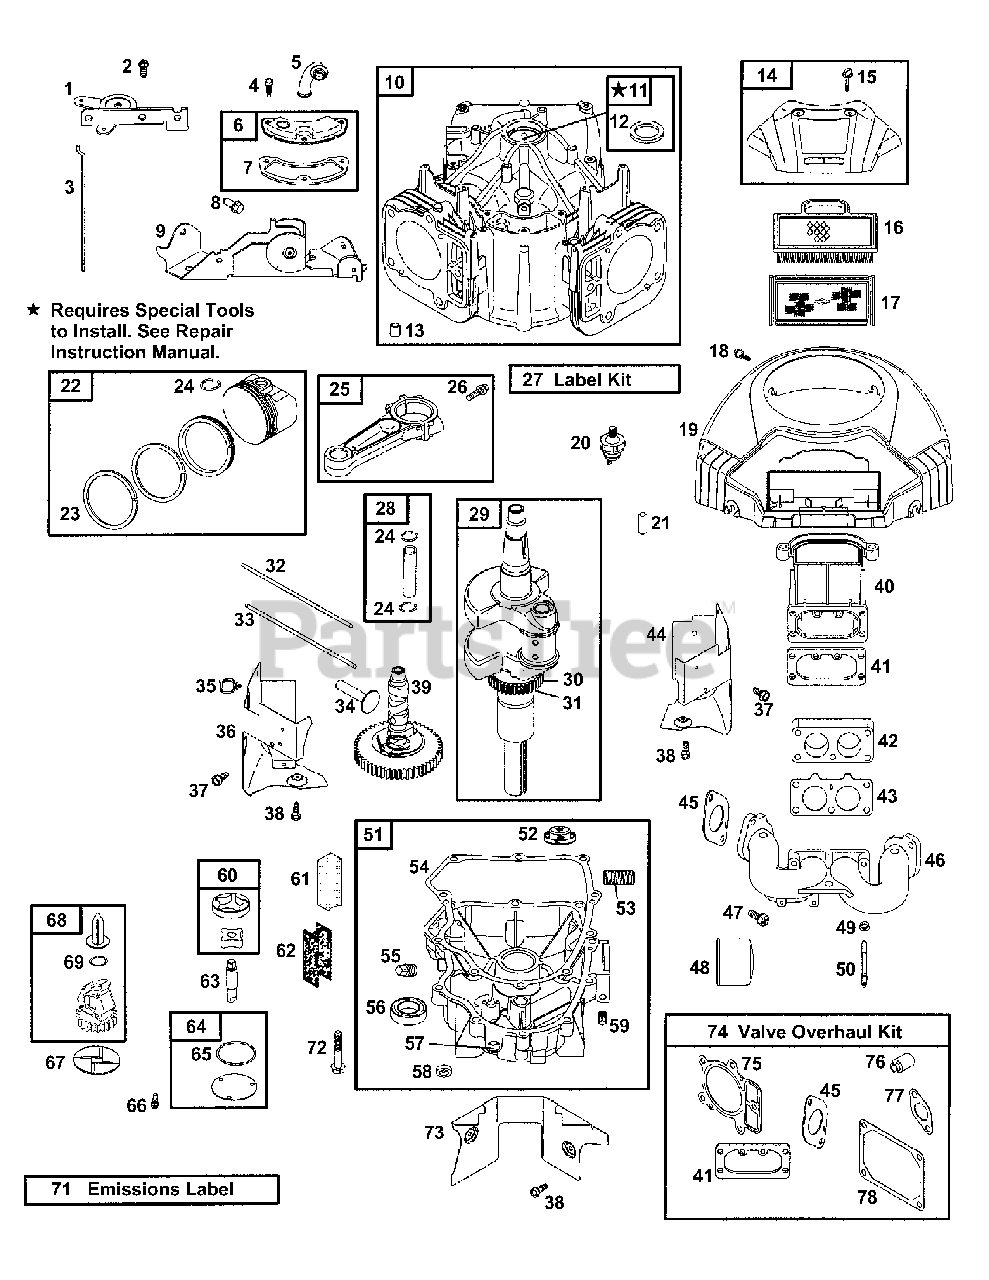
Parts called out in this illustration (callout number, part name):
1	Choke Control Bracket
2	Screw (Choke Control Bracket)
3	Choke Link
4	Screw (Breather Assembly)
5	Breather Tube
6	Breather Assembly
7	Breather Gasket
8	Screw (Control Bracket)
9	Control Bracket
10	Cylinder Assembly
11	Bushing/Seal Kit (Magneto Side)
12	Oil Seal (Magneto Side)
13	Locating Pin
14	Air Cleaner Cover
15	Air Cleaner Knob
16	Air Cleaner Cartridge Filter
17	Pre-Cleaner Filter
18	Screw (Blower Housing)
19	Blower Housing
20	Oil Pressure Switch
21	Flywheel Key
22	Piston Assembly (Standard)
22	Piston Assy. (.010 Oversize)
22	Piston Assy. (.020 Oversize)
22	Piston Assy. (.030 Oversize)
23	Ring Set (Standard)
23	Ring Set (.010 Oversize)
23	Ring Set (.020 Oversize)
23	Ring Set (.030 Oversize)
24	Piston Pin Lock
25	Connecting Rod
26	Screw (Connecting Rod)
28	Piston Pin
29	Crankshaft
30	Timing Key
31	Timing Gear
32	Rod-Push (Steel)
33	Rod-Push (Aluminum)
34	Valve Tappet
36	Air Guide Cover (Cylinder #1)
37	Screw (Air Guide Cover)
38	Screw (Air Guide Cover)
39	Camshaft
40	Air Adapter
41	Air Cleaner Gasket
42	Carburetor Spacer
43	Intake Gasket
44	Air Guide Cover (Cylinder #2)
45	Intake Gasket
46	Intake Manifold
47	Screw (Intake Manifold)
48	Oil Filter
49	Nut (Carburetor)
50	Stud (Carburetor)
51	Engine Sump
52	Oil Pump Screen
53	Oil Filter Nipple
54	Crankcase Gasket
55	Oil Drain Plug
56	Oil Seal (PTO Side)
57	Governor Crank Bushing
58	Governor Shaft Seal
59	Oil Plug
60	Oil Pump
61	Oil Collector
62	Breather Retainer
63	Pump Shaft
64	Oil Pump Cover
65	O-Ring Seal (Oil Pump Cover)
66	Screw (Oil Pump Cover)
67	Washer (Governor Gear)
68	Governor Gear
69	Governor Shaft Retainer
71	Emissions Label
72	Screw (Engine Sump)
73	Air Guide Cover
74	Valve Overhaul Kit
75	Cylinder Head Gasket
76	Valve Seal
77	Exhaust Gasket
78	Rocker Cover Gasket
